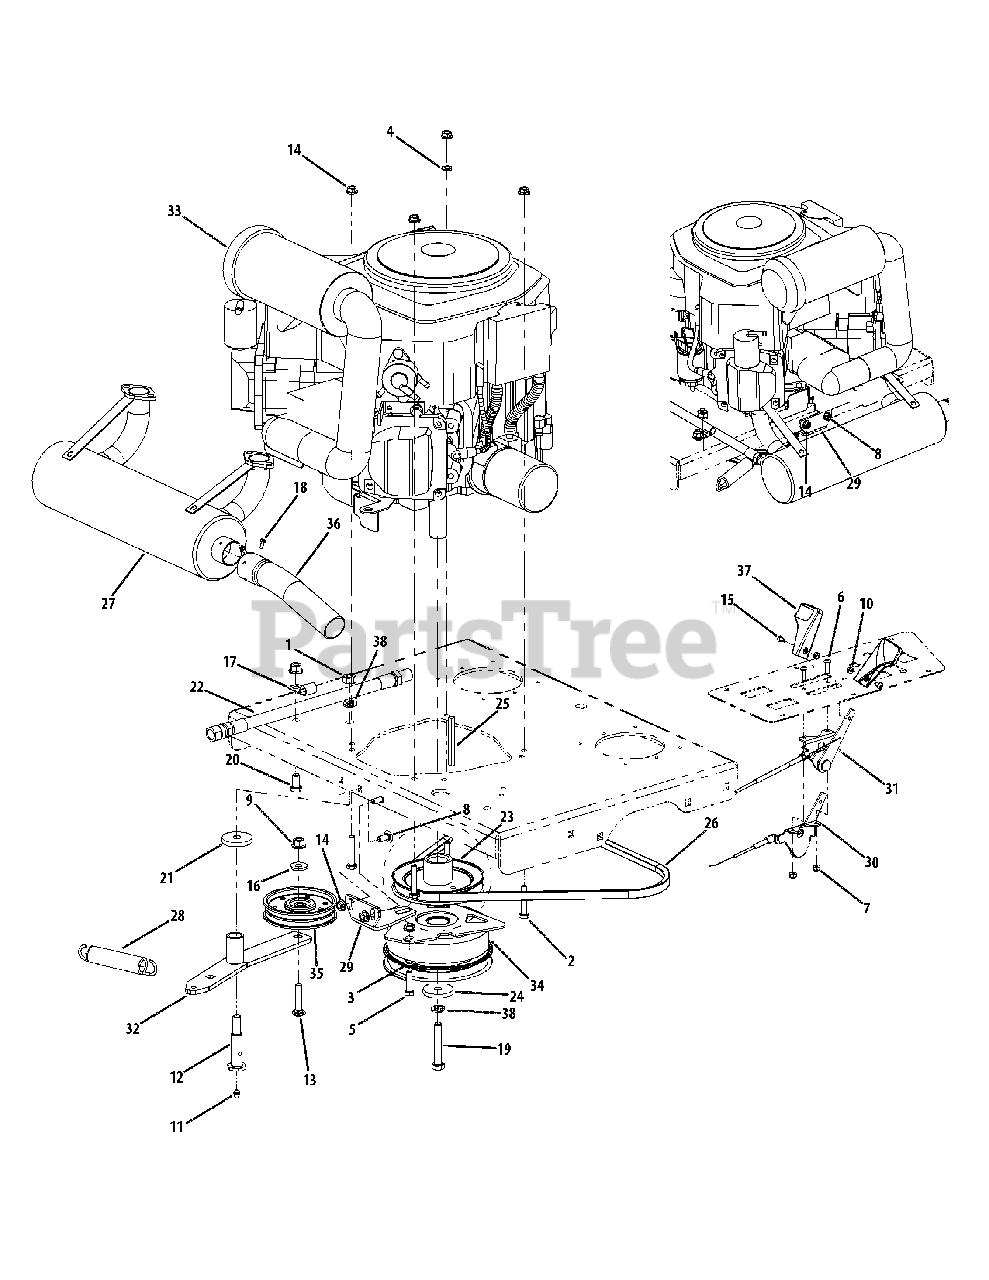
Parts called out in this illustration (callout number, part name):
1	Hex Nut, 7/16-14
2	HHCS, 5/16-18, 1-3/4
3	Flat Washer, 5/16
4	Flat Washer, 5/16
5	HHCS, 5/16-18 x 1-1/4
6	Machine Screw, 10-32 x 5/8
7	Lock Nut, Nylon Insert, 10-32
8	Carriage Bolt, 5/16-18 x .75
9	Flange Lock, Hex Nut, 3/8-16
10	Nut Washer, W/Star, 8-32
11	Grease Fitting, 1/4-28 x 3/16
12	Shoulder Screw, 7/16-14
13	Hex Carriage Screw, 3/8-16, 1.75
14	Hex flange Lock Nut, 5/16-18
15	Machine Screw, 8-32, .375
16	Flat Washer, .406 ID, 1.0 OD, .105
17	Clip, Heat Shield Cable
18	Screw, #10-16 x 0.500
19	Cap screw, 7/16-20 x 2.50
20	Hex Cap Screw, 3/8-16, .750
21	Flat Washer, 7/16 ID x 1.75 OD x .25
22	Oil Drain Hose
23	Pump Drive Pulley
24	Flat Washer, 7/16 ID x 1.75 OD x .25
25	Key, 1/4 x 1/4 x 3
26	Belt, 51.2 Lg
27	Muffler Accessory Kohler
28	Extension Spring, .98 OD x 5.00
29	Retainer Clutch Assembly, Ogura
30	Throttle, Control Cable
31	Choke Control Cable
32	Engine Idler Arm
32	Bearing
33	Engine, 27HP Kohler
34	Clutch Brake, 1.125 ID
35	Flat Pulley with Flanges
36	Muffler Accessory Exhaust Tube
37	Control Throttle Knob
38	Lock Washer, 7/16
